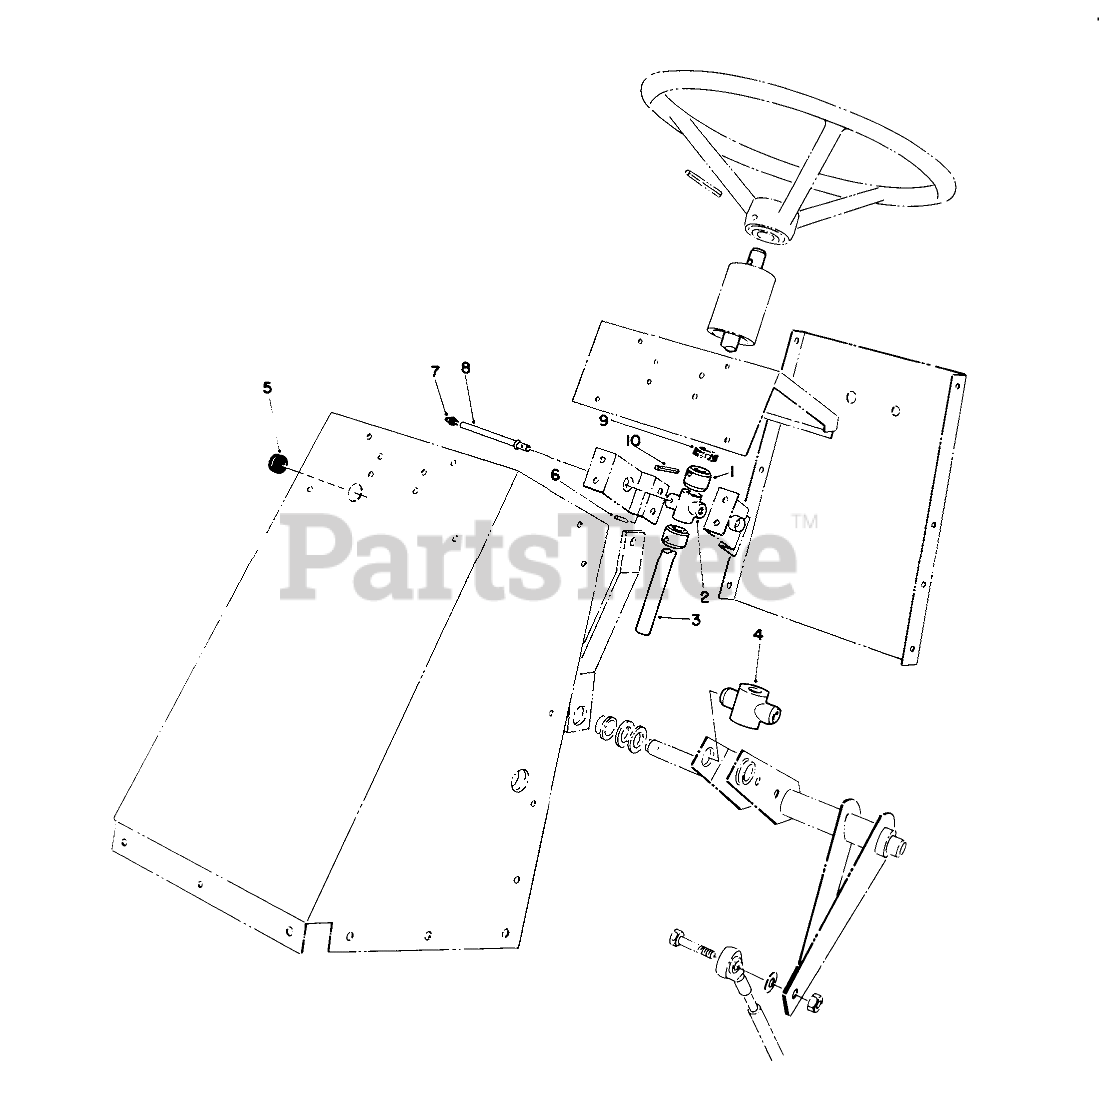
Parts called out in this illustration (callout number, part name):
1	STRG SHAFT COLLAR
2	BRG STEERING SHAFT
3	Shaft-Steering
4	STEER.SHAFT FOLLOWER
5	GROMMET
6	3/32 X 9/16 ROLL PIN
7	FITTING-GREASE
8	TUBE ZERK
9	COVER-DUST
10	PIN-SPRING
